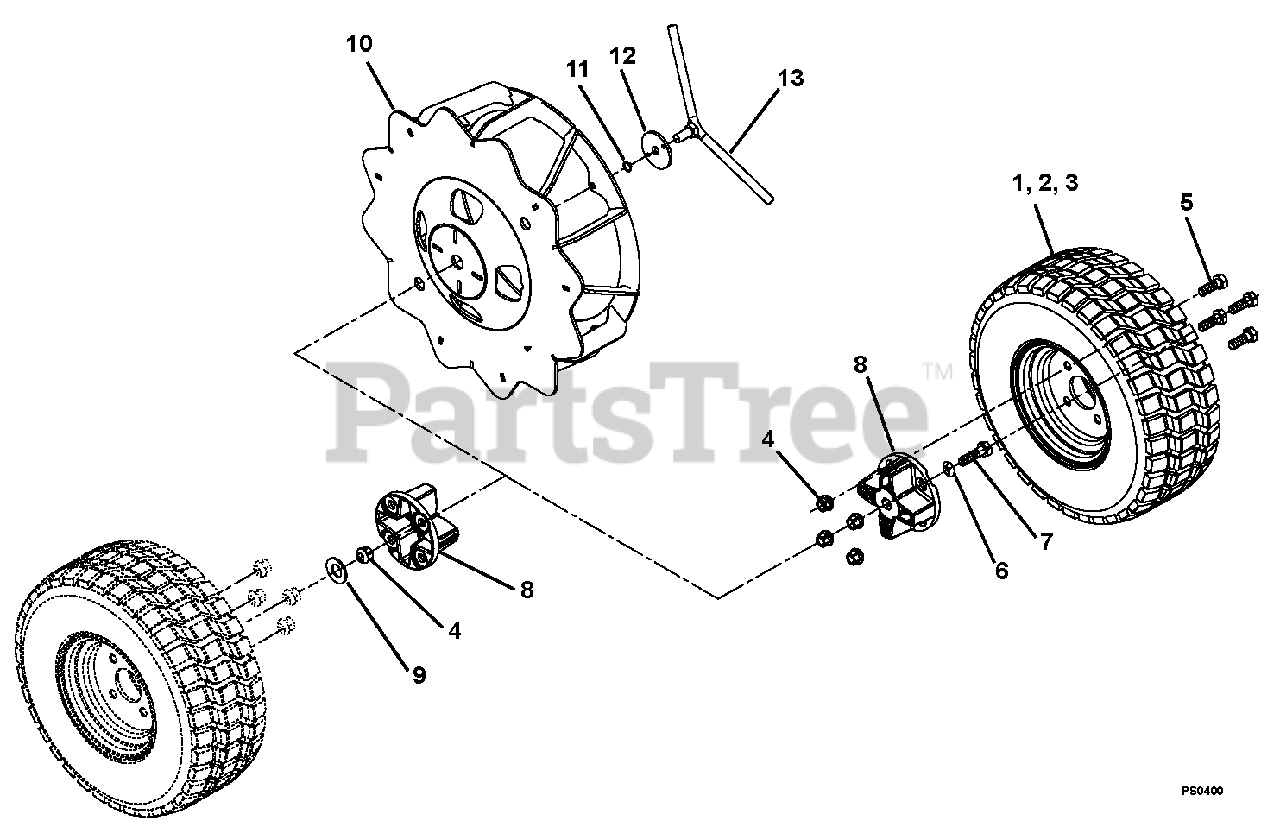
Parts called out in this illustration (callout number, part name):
1	Disc Wheel
3	Tyre Tube
5	Bolt, Hex D961 M14 x 1, 5 x 40
6	Washer, Spring D74361C M14
7	Bolt, Hex D960 M14 x 1, 5 x 40
8	Driving Flange
9	Washer, Spring D2093B 45 x 22,4
10	Cage Wheel
13	Handle Screw
